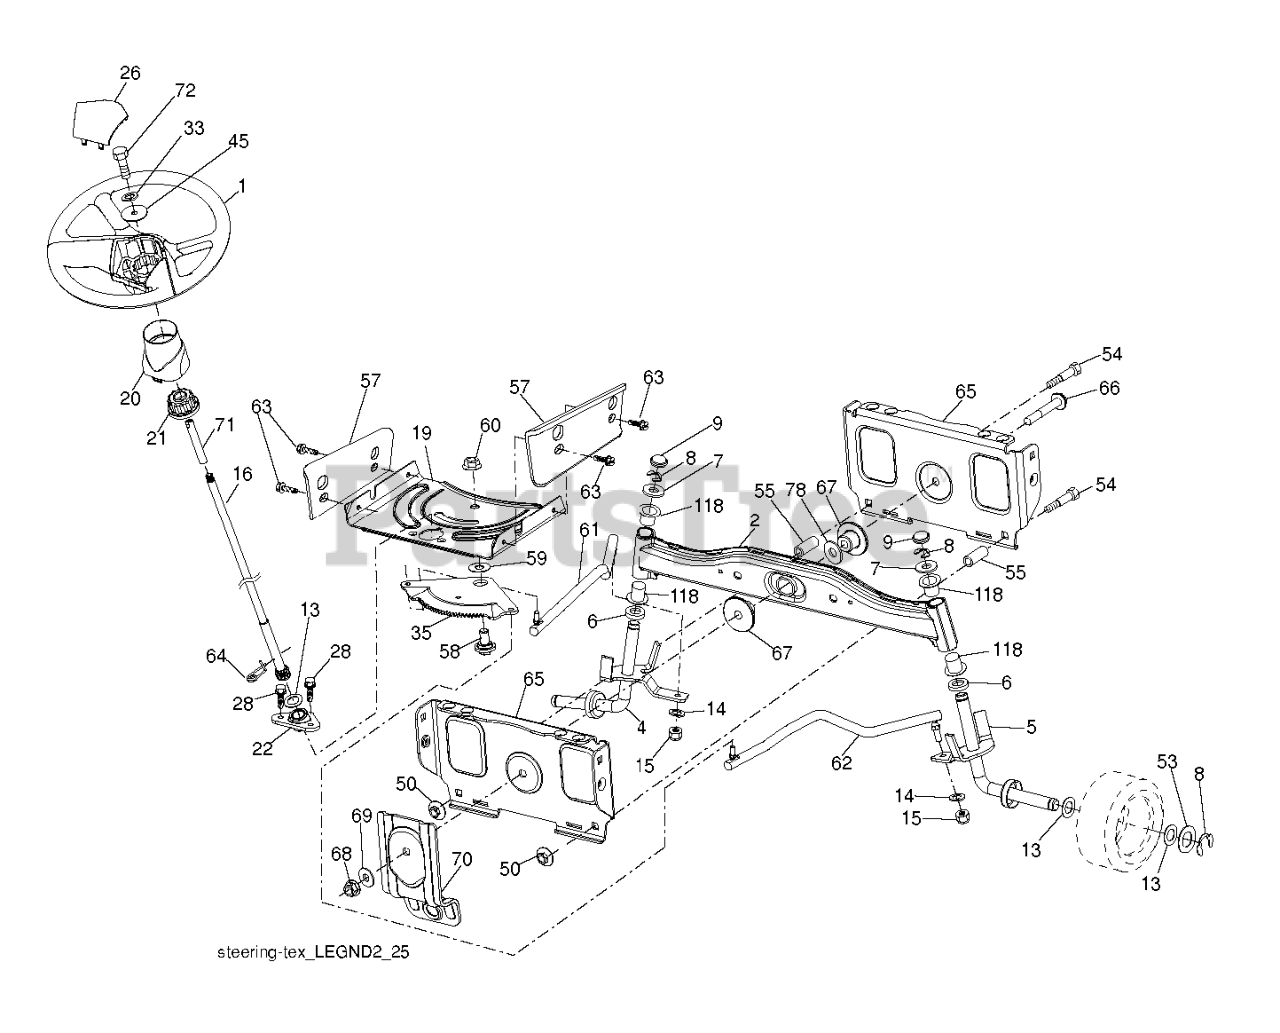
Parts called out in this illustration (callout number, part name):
1	WHEEL.STEERING.LEGEND2.GRY
2	AXLE ASSY FRONT
4	SPINDLE.WELDED.LH.15"TEX
5	SPINDLE.WELDED.RH.15"T
6	THRUST WASHER
9	CAP.SPINDLE.BLACK
14	WASHER, LOCK 3/8
15	NUT CROWNLOCK 3/8-24
16	SHAFT STEERING
19	PLATE.STEER.DDL.NLT/NG
20	BOOT, STEERING
21	ADAPTER, WHEEL STNG..
22	BUSHING.ASM.STEERING.A
26	INSERT.CAP.STRG.WH.GRAY
28	SCREW, 3/8-16X3/4
33	WASHER.LOCK.HVY.HLCL.SPR.5/16
35	GEAR.SECTOR.PLATE.DDL.
45	WASHER.11/32
50	NUT LOCK FLG 3/8-16 UNC
53	WASHER.HARDENED
55	SPACER.BRACE.AXLE
57	BRACKET.UPSTOP.TEX
58	BOLT.SHOULDER.SECTOR.P
59	WASHER.THURST.SECTOR.S
60	NUT FLANGE LOCK 5/8-11
61	DRAGLINK.LH.BALLSTUD.D
62	DRAGLINK.RH.BALLSTUD.D
63	SCREW
64	RETAINER.CLIP.SPRING.S
65	BRACE.AXLE.FRONT.NLT/N
66	BOLT HEX FGHD 7/16-14 X 3 SERR
67	BUSHING.PM.FRONT AXLE
68	NUT.LOCK.FLANGE.7/16
69	WASHER.1.5X.505X.118
70	BRKT.DECK.SUSPENSION.F
71	SHAFT EXTENSION STEERING
72	BOLT YT
78	THRUST WASHER
118	BUSHING, AXLE CAST
